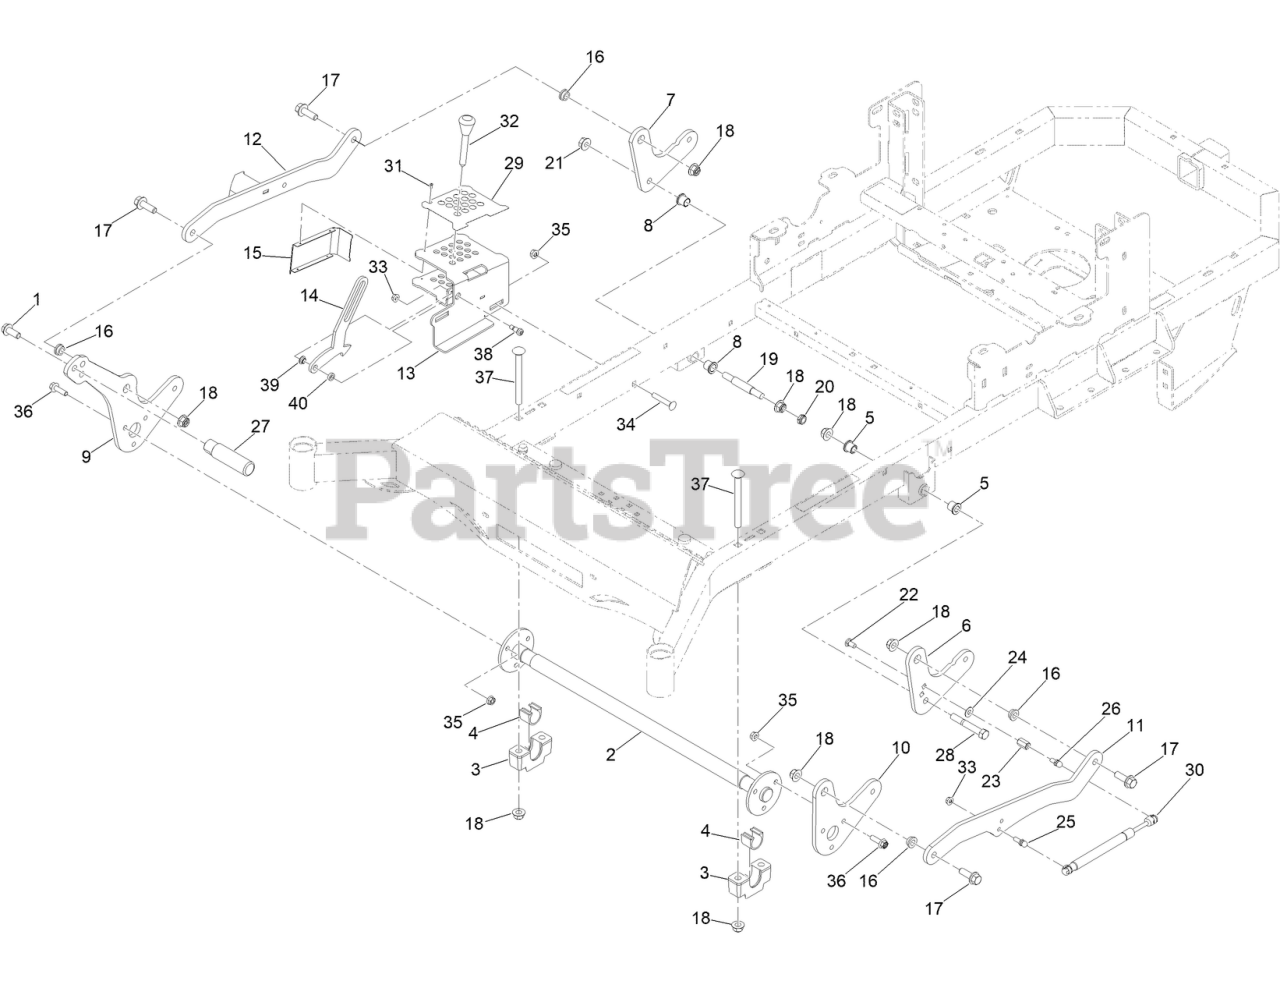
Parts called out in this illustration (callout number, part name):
1	1/2-13X1.25IN HEX FLANGE BOLT (GR.8) YZ
2	DECKLIFT ASM-FRONT
3	SUPPORT-BEARING HOUSING
4	BEARING-CROSS SHAFT, FRONT
5	BUSHING-FLANGE
6	(RZ REAR HOC HANGER)
7	ARM-DECKLIFT REAR (3/8")
8	BUSHING-FLANGE
9	LEVER-LIFT
10	PLATE-DECKLIFT, ARM LH
11	LINK-HOC(LEFT SIDE)
12	LINK ASM-HOC(RIGHT SIDE WELDED)
13	BRACKET-HOC ASM [BLK-TXT]
14	PLATE-TRANSPORT LOCK
15	COVER-HOC
16	1/2IN ID X 3/4IN OD X 3/8IN FLANGE BUSH
17	SCREW-HHF
18	1/2-13 HEX FLANGE 2-WAY REV CNTR L/NYZ
19	RR DECK HEIGHT BOLT (MACHINED)
20	NUT-HEX
21	NUT-HHF
22	3/8 X 3/4IN GR 8 CARR BOLT ZINC
23	HEX COUPLING NUT - REDUCER (3/8" TO 5/16
24	WASHER-FLAT
25	5/16-18X1.286 DAMPER BALL STUD (.562 TL)
26	5/16-18X1.286 DAMPER BALL STUD (.562 TL)
28	1/2-13 X 3-1/2 HEX C/S GR 5 ZINC YELLOW
29	DECAL-HEIGHT OF CUT
30	RZ DECK ASSIST GAS SPRING
31	RIVET
32	MAGNETIC PIN FOR STAND ON MWR
34	SCREW-CARR
36	SCREW-HHF
37	SCREW-CARR
38	3/8 X 1/2 SOCKET SHOULDER BOLT YZ
39	BUSHING-FLANGE
40	WASHER-PLAIN
